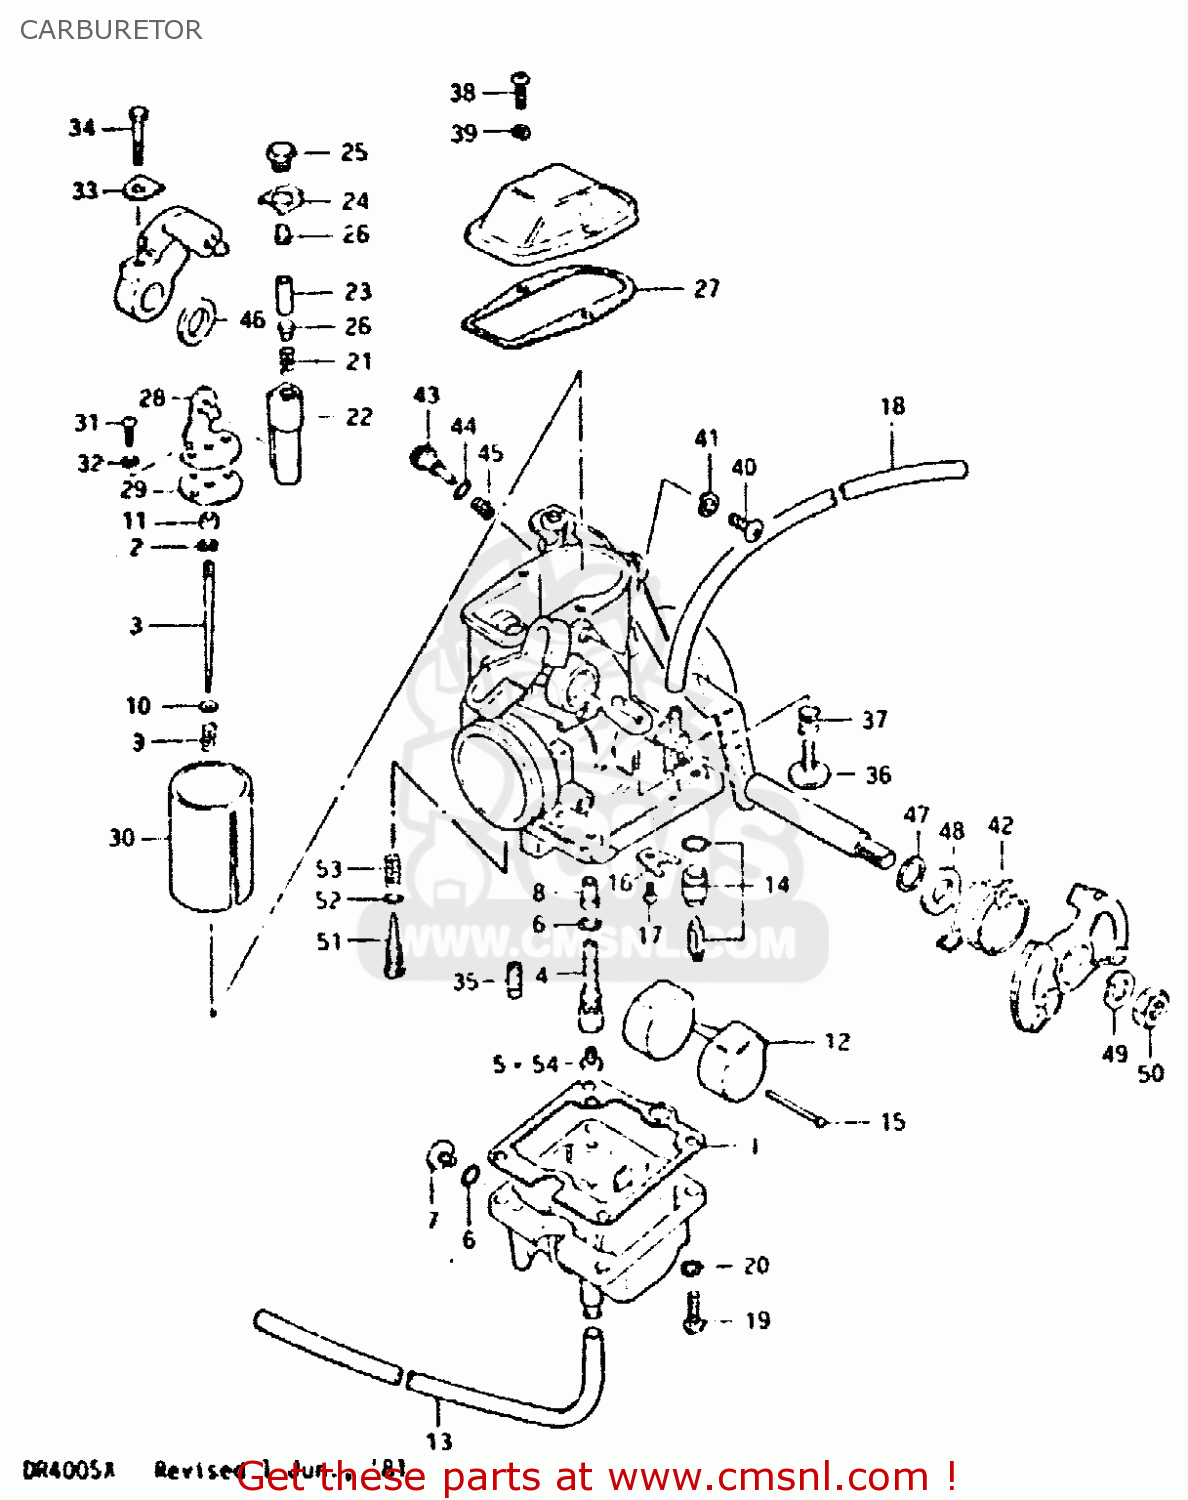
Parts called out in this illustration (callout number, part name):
1	GASKET,FLOAT CAHMBER (NAS)
2	CLIP
3	NEEDLE, JET (6G1-3)
4	PIPE,BLEEDER
5	JET
6	O RING
7	SCREW
8	JET, NEEDLE (P-2)
9	SPRING
10	WASHER,JET NEEDLE
11	RING
12	FLOAT
13	HOSE
14	VALVE ASSY,NEEDLE
15	PIN,FLOAT
16	PLATE
17	SCREW 4X6
18	HOSE
19	SCREW
20	LOCK WASHER
21	SPRING,CARBURETOR
22	LEVER ASSEMBLY
23	SPRING
24	PLATE,CARBURETOR
25	SCREW
26	PIN,CARBURETOR
27	GASKET,MIXING CHAMBER
28	BRACKET,CARBURETOR
29	PLATE,THROTTLE VALVE
30	VALVE,THROTTLE
31	SCREW
32	LOCK WASHER
33	RING
34	BOLT
35	JET
36	ADJUSTER
37	SPRING,THROTTLE SCREW
38	SCREW
39	LOCK WASHER
40	SCREW
41	LOCK WASHER
42	SPRING,THROTTLE VALVE
43	SCREW,PILOT AIR ADJUSTING
44	O RING
45	SPRING
46	RING
47	SEAL
48	RING
49	LOCK WASHER
50	NUT
54	JET
